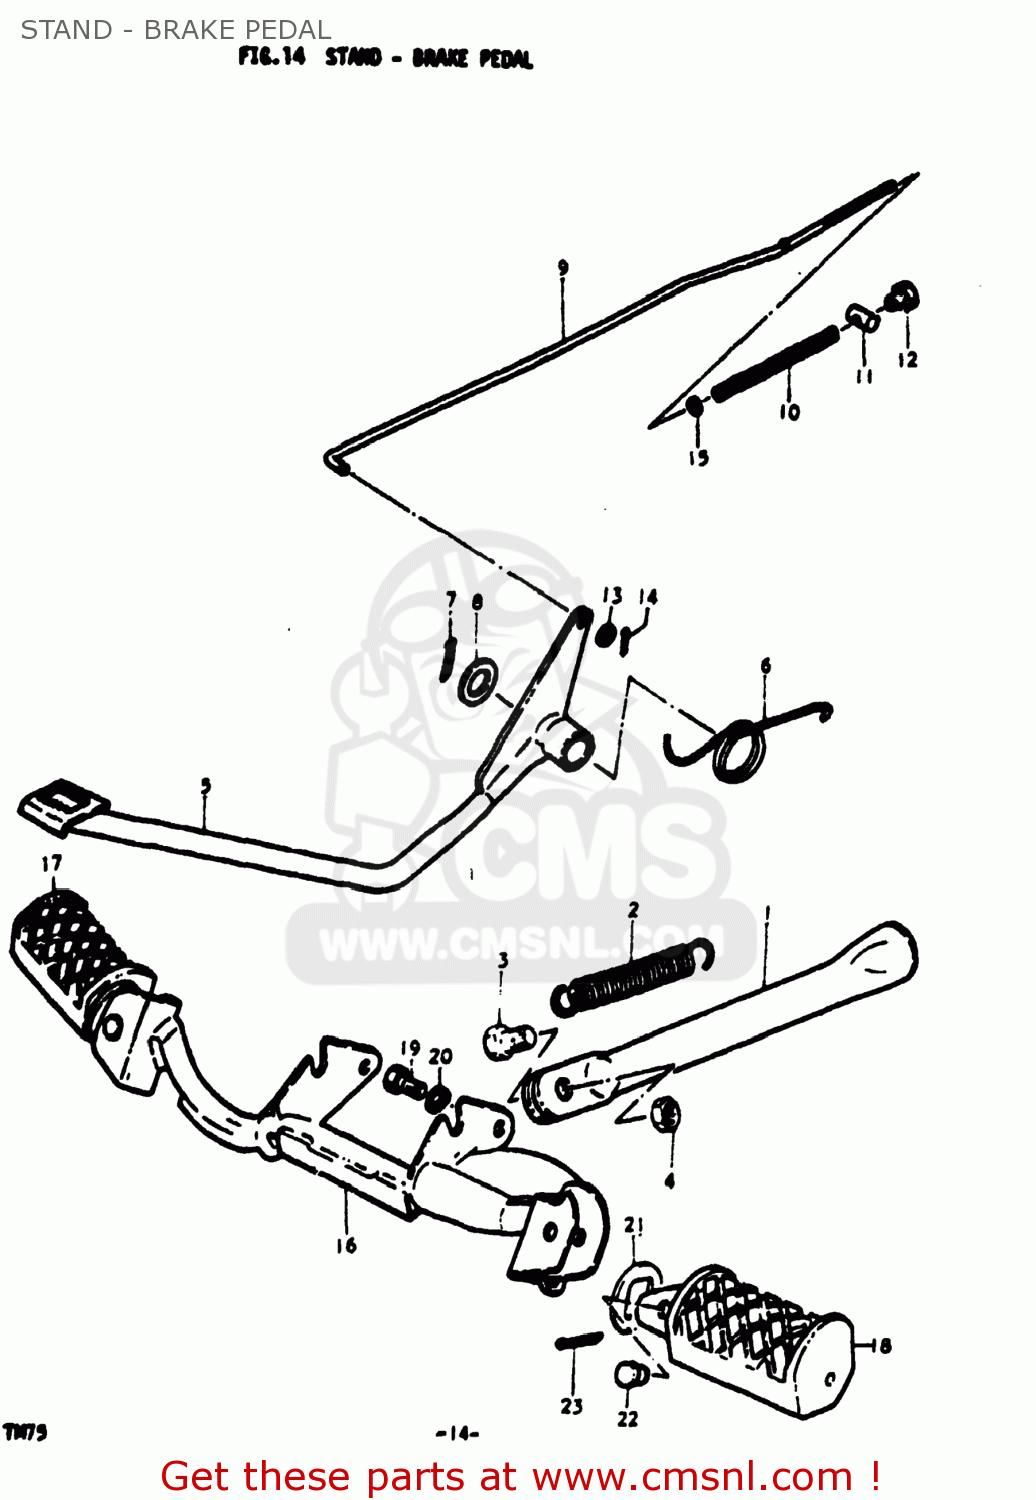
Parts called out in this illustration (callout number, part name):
1	STAND,SIDE
2	SPRING
3	BOLT
4	NUT
5	PEDAL,BRAKE
6	SPRING
7	COTTER PIN
8	WASHER(15.5X26X2.3)
9	ROD ASSEMBLY,REAR BRAKE
10	SPRING
11	PIN(11X18)
12	NUT
13	WASHER
14	PIN 20X20
15	WASHER
16	BAR,FRONT FOOTREST
17	RUBBER,FOOTREST,RIGHT
18	RUBBER,FOOTREST,LEFT
19	BOLT
20	LOCK WASHER
21	WASHER
22	PIN
23	PIN 20X20
